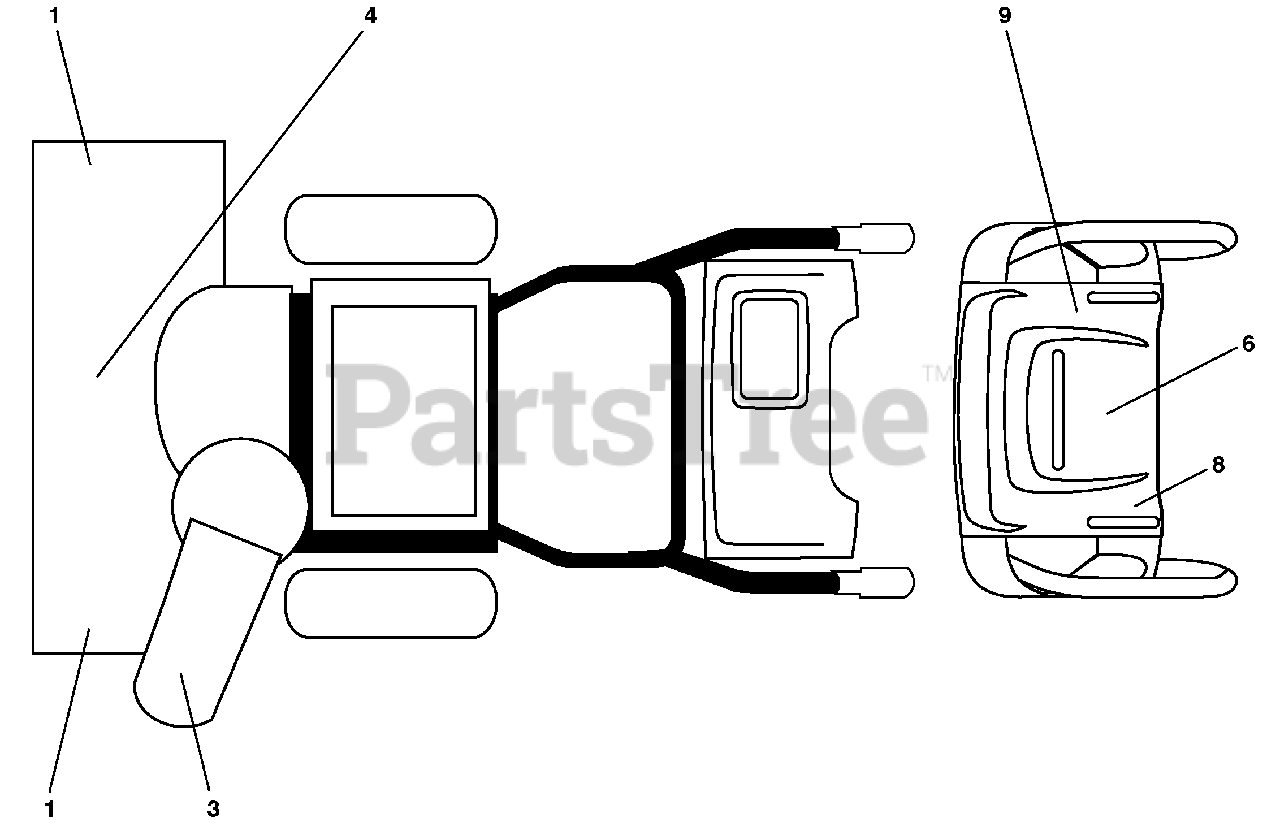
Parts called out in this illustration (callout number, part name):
1	DECAL, DANGER
3	DECAL, DANGER, DEFLECTOR
4	DECAL, DANGER
6	DECAL, INSTRUCTION
8	DECAL, CONS, LT SPD/LEV/PWRST
9	DECAL, CONS, RT SPD/LEV/PWRST
9	OWNER'S MANUAL, ENGLISH
9	OWNER'S MANUAL, FRENCH
